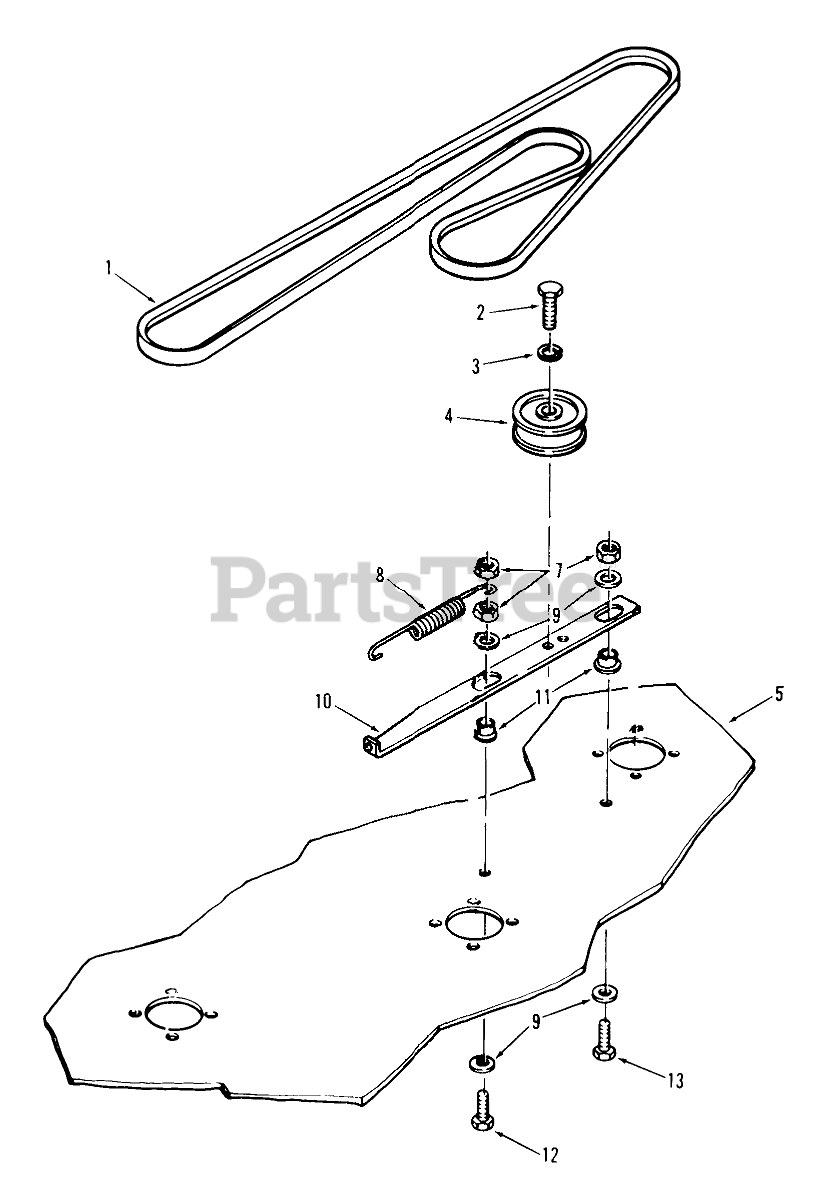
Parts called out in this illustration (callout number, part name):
1	V-BELT
2	Bolt
3	LOCKWASHER
4	Idler Pulley
5	Mower Deck Assembly
7	Nut
8	SPRING-EXTENSION
9	WASHER
10	BAR-IDLER SUPPORT
11	Bushing/Spacer
12	Bolt
13	Bolt
